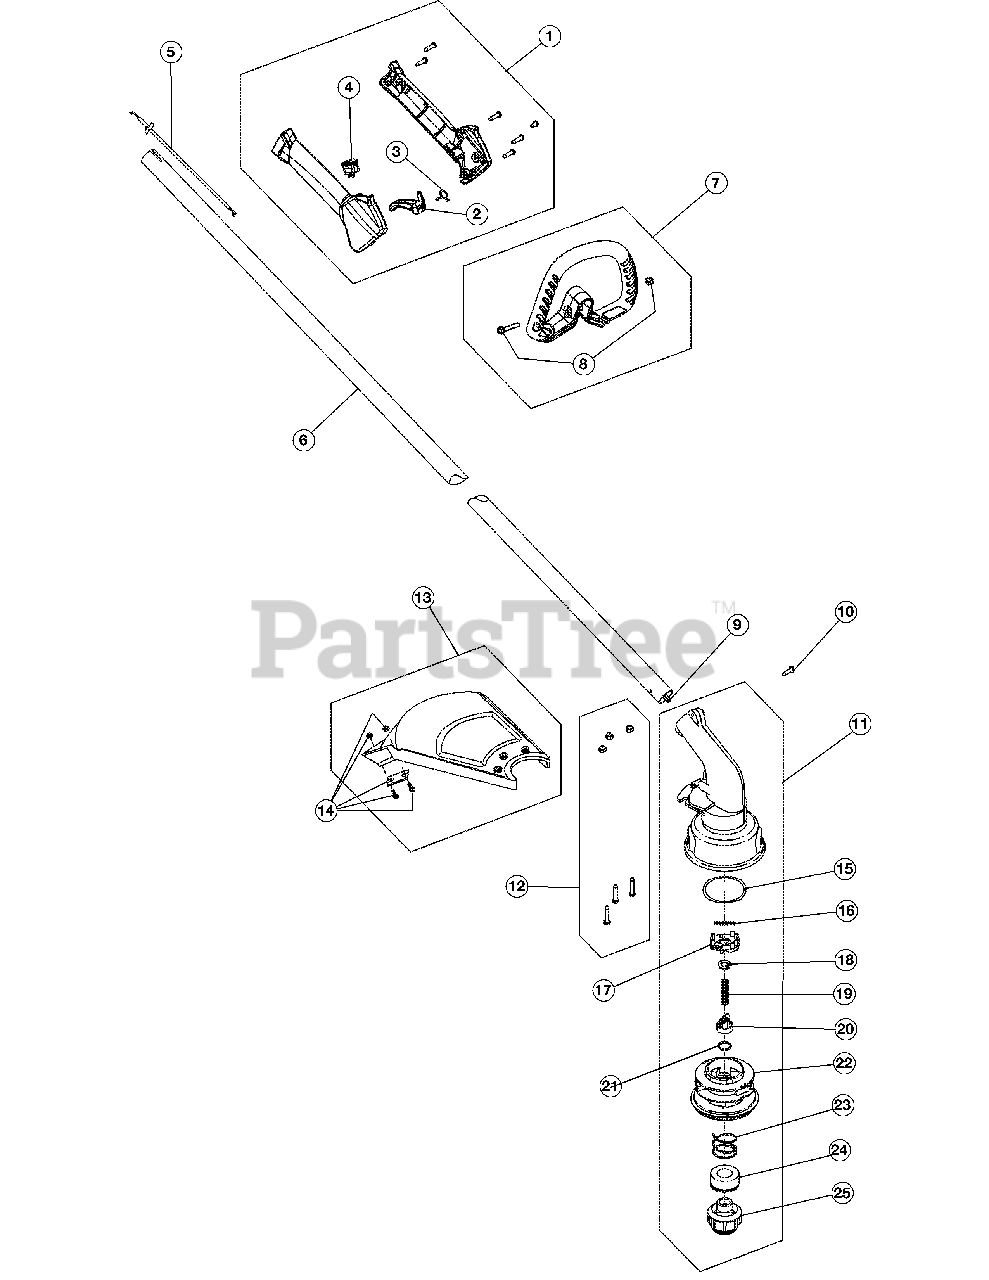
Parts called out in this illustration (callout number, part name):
1	Throttle Housing Assembly (Incl. Ref No. 2-4)
2	Throttle Trigger
3	Throttle Trigger Spring
4	Switch Assembly
5	Throttle Cable Assembly
6	Drive Shaft Housing
7	D-Handle Assembly (Incl. Ref No. 8)
9	Flexible Drive Shaft
10	Anti-Rotation Screw
11	Gear Box Assembly (Incl. Ref No. 15-25)
12	Shield Mounting Hardware
13	Shield Assembly (Incl. Ref No. 14)
14	Blade Assembly
15	Thrust Washer
16	Slider
17	Small Spring
20	Plunger
22	Inner Reel
23	Large Spring
24	Foam Seal
25	Bump Knob Assembly (Incl. Ref No. 23 & 24)
